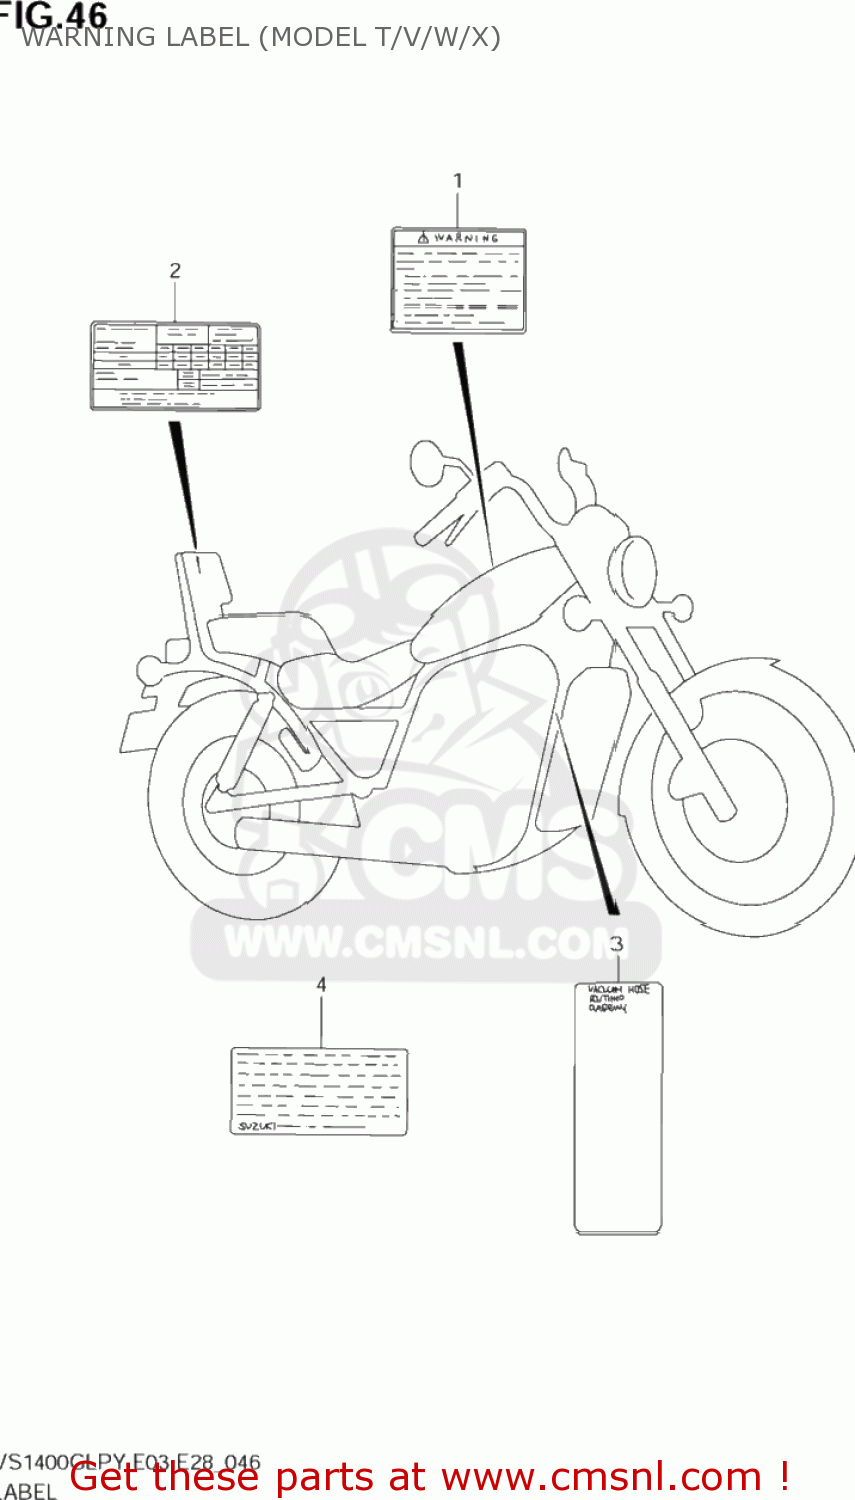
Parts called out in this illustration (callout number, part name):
1	LABEL,WARNING SAFETY
2	LABEL,TIRE INFORMATION
3	LABEL (VACUUM HOSE ROUTING)
4	LABEL (MANUAL NOTICE)
5	O.M. VS1400GLP
